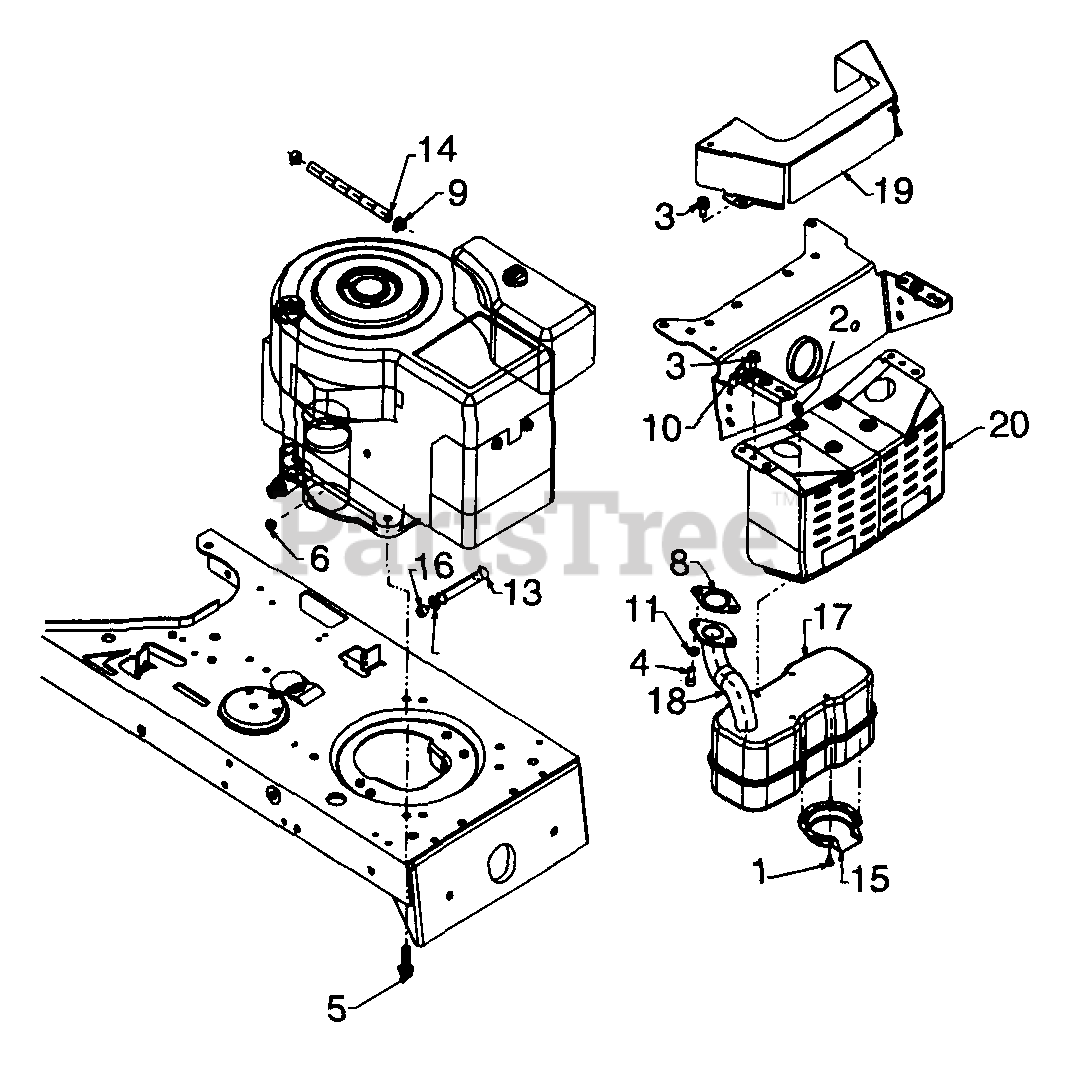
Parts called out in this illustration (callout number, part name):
1	Hex Bolt #8-32 x .38" Lg.
2	Hex Wash. Hd. TT-Scr. 1/4-20 x .5" Lg.
3	Hex Wash. Hd. TT-Scr. 5/16-18 x .62"
4	Socket Hd. Bolt 5/16-18 x .62" Lg.
5	Hex Wash. Hd. TT-Scr. 3/8-16 x 1.25"
6	Hex Sems Nut 1/4-20 Thd.
8	Exhaust Gasket
9	Hose Clamp
10	Clamp
11	L-Wash. 5/16" I.D.
13	Pipe 3/8 NPT x 3.8" Lg. (16/17 HP)
14	Fuel Line
15	Muffler Deflector
16	Hex Pipe Plug (16/17 HP)
17	Muffler
18	Exhaust Pipe (16/17 HP)
